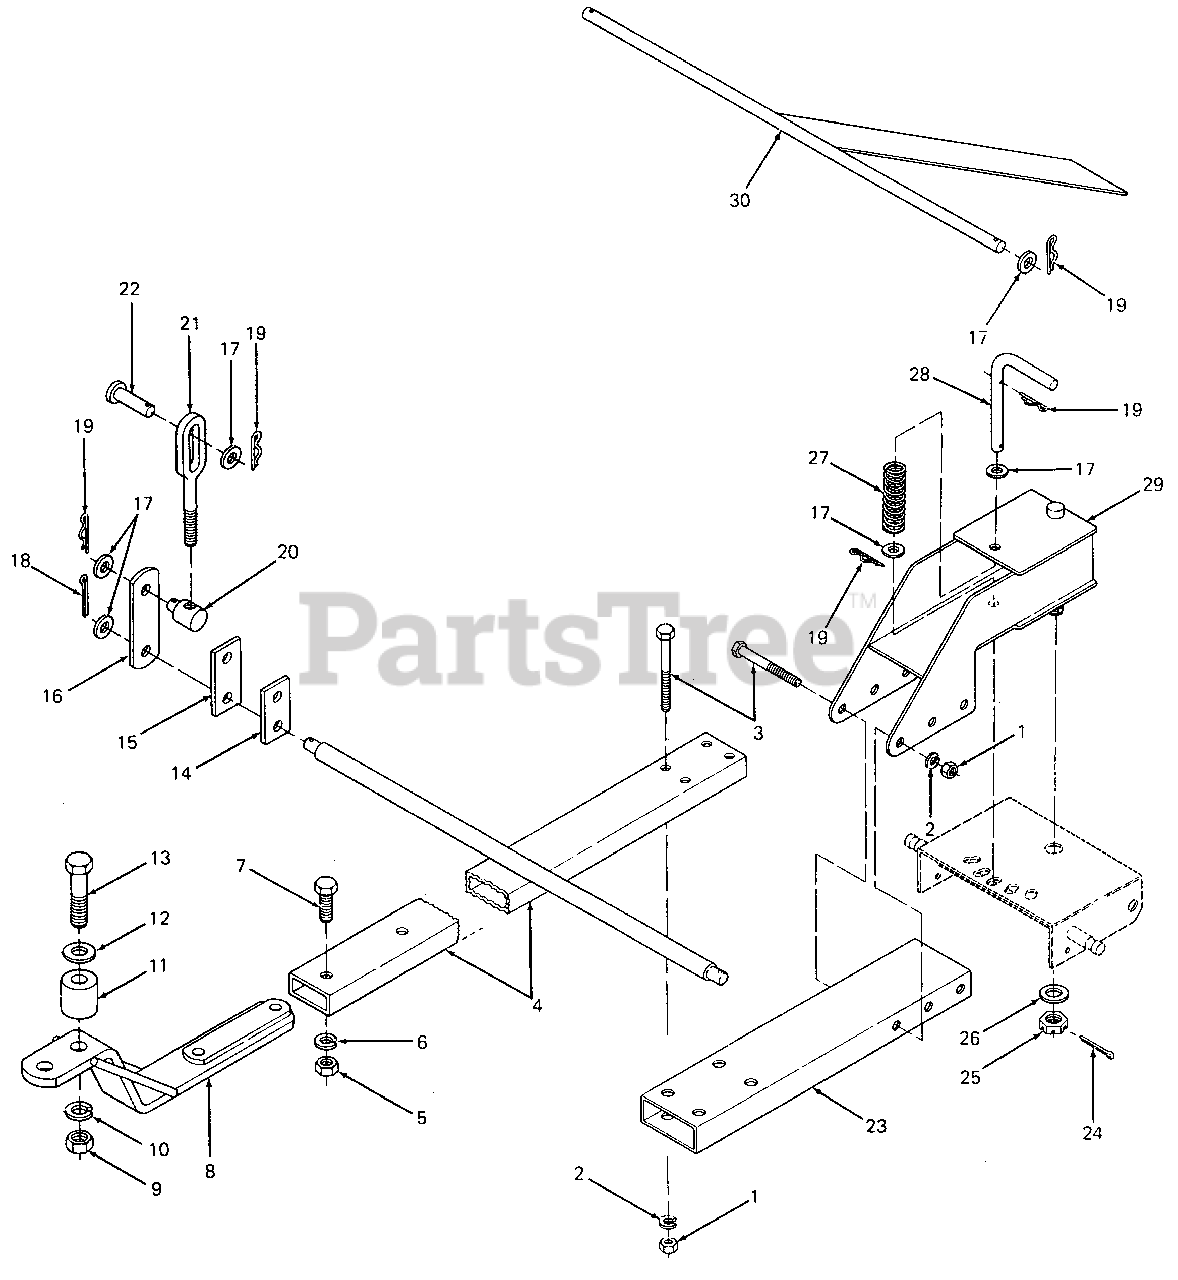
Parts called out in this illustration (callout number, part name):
1	Nut, Hex, 3/8-24
2	Washer, Lock, 3/8
3	Screw, Hex Cap, 3/8-24 X 3.75 Lg GR5
4	Bracket, Lift
5	Nut, Hex Jam, 1/2-13
6	Washer, Lock, 1/2
7	Screw, Hex Cap, 1/2-13 X 1.5 Lg GR5
8	Bracket, Hanging
9	Nut, Hex Insert Lock, 5/8-18
10	Washer, Lock, 5/8
11	Spacer, .65 X 1.5 X 1.5 Lg
12	Washer, Flat, .64 X 1.25 X .100 Thk
13	Screw, Hex Cap, 5/8-18 X 3.0 Lg GR5
14	Link, Lift
15	Link, Lift
16	Link, Lift
17	Washer, Flat, .510 X 1.0 X .060 Thk
18	Pin, Cotter, 1/8 Dia X 1.25 Lg
19	Pin, Internal Cotter
20	Ferrule, Adjustment, 1/2-20 Trd
21	Link, Adjustment
22	Pin, Lift Bracket
23	Tubing, Rectangular, 2 X 3 X 21.0 Lg
24	Pin, Cotter, 1/8 Dia X 1-5/8 Lg
25	Nut, Hex Castle, 3/4-16 GR5
26	Washer, Flat, .812 X 1.47 X .108 Thk
27	Spring, Compression
28	Handle, Pivot Bracket
29	Bracket, Pivot
30	Plate, Guide
